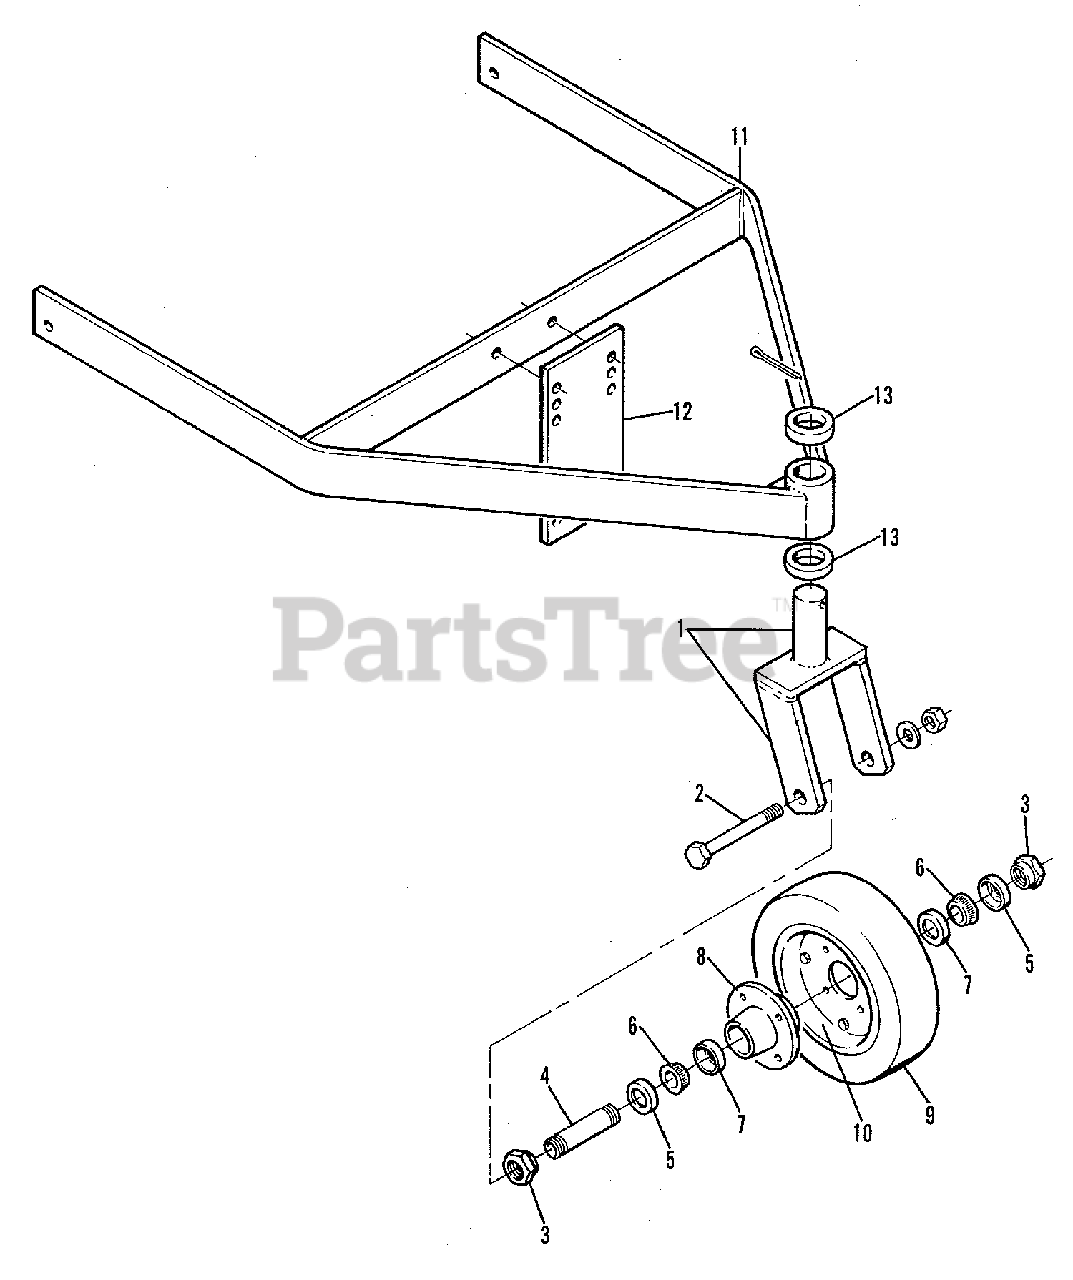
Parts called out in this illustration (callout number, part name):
1	YOKE ASSEMBLY
1	PIN, Cotter, 3/8 x 3
2	BOLT ASSEMBLY, Axle
3	NUT, Shoulder
4	SPACER, Axle Bolt
6	CONE, Bearing
7	CUP, Bearing
8	CAPSCREW, 1/2NC x 1-1/2
8	LOCKWASHER, 1/2
10	DISK, Wheel
11	FRAME ASSEMBLY, Wheel
11	CAPSCREW, 5/8NC x 2
11	LOCKWASHER, 5/8
12	BRACKET, Adjusting
12	CAPSCREW, 5/8NC x 2
12	LOCKWASHER, 5/8
13	WASHER, Yoke Assembly
